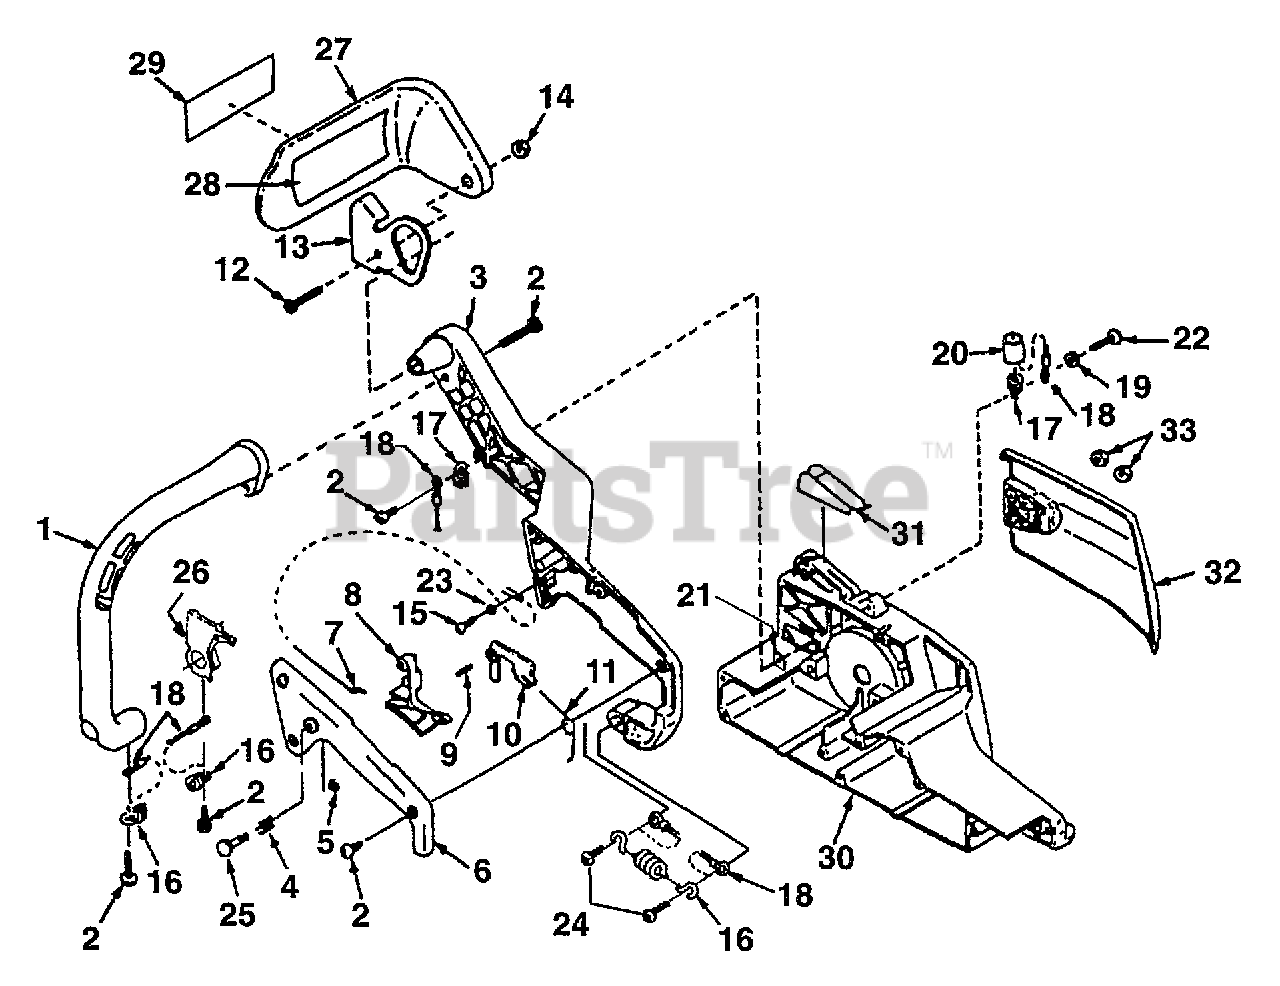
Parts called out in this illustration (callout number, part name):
1	HANDLE BAR
2	SCREW, Thread Form (8-16 X 5/8")
3	HANDLE-Rear
4	SPRING-Compression
5	RING, Retaining
6	COVER-Rear Handle
7	CABLE-Throttle
8	TRIGGER & SWIVEL
9	PIN-Dowel
10	LOCK-Trigger
11	SPRING-Trottle
12	SCREW-Hex Cap
13	MOUNTING BRACKET-Handguard
14	NUT-Flange Hex
15	SCREW, Thread Form (#6-19 X 7/8")
16	SPRING-Extension
17	SPRING-Extension
18	RETAINER-Spring
19	WASHER-Flat (#10)
20	SLEEVE-Spring
21	NUT-Square (#10-24)
22	SCREW-Pan Hd. (#10-24 X 7/8")
23	WASHER-Flat
24	SCREW-Thread Form (8-16 X 1/2)
25	PIN-Throttle Lock
26	HOUSING-Starter Side
27	HANDGUARD
28	DECAL-Kickback
29	DECAL-Kickback
30	ENGINE HOUSING-(Drive Side)
31	COVER-Snap On
32	DRIVE CASE COVER
33	NUT-Hex (5/16"-18)
